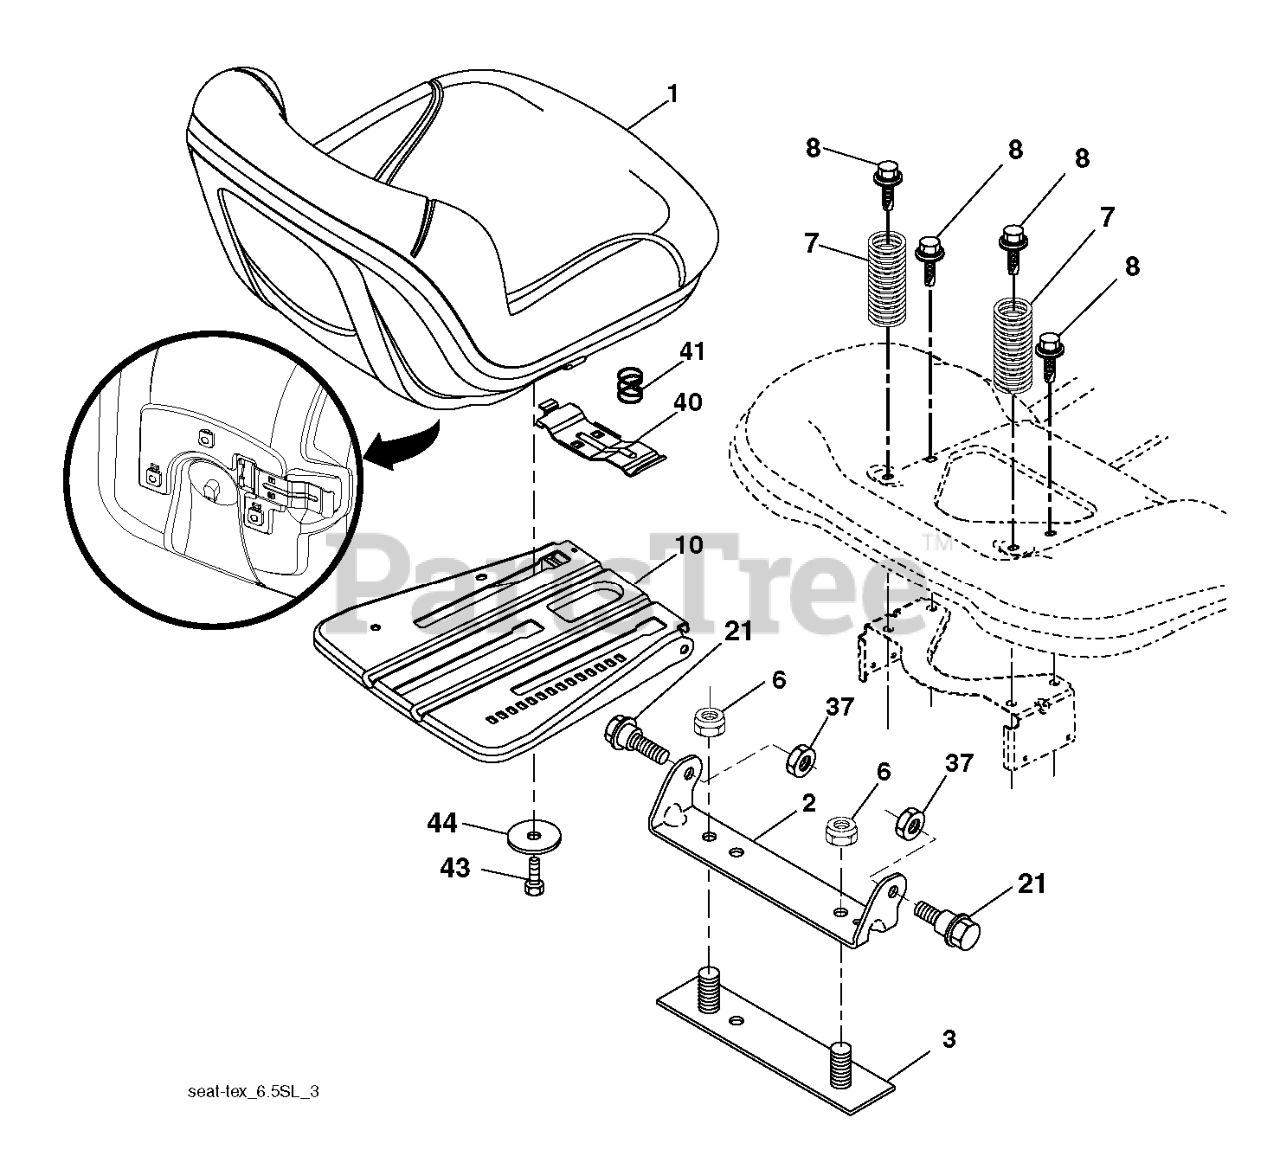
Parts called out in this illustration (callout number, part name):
1	SEAT.TH150.MS498.GRY.HUSQ.TEX
2	BRKT.PIVOT.FENDER
3	STRAP
6	NUT
7	SPRING COMPRESSION
8	BOLT.5/16-18UNCX3/4 W/SEMS.BLK
10	PAN.ASM.SEAT.3PT
21	BOLT.SHOULDER.5/16-18
37	NUT.71038.31-18.HEX.NYLOCK
40	HANDLE.SLIDE.SEAT.TEX.GREY
41	SPRING.LATCH.SEAT.TEX
44	WASHER 13/32 X 2-3/8 X 12GA
